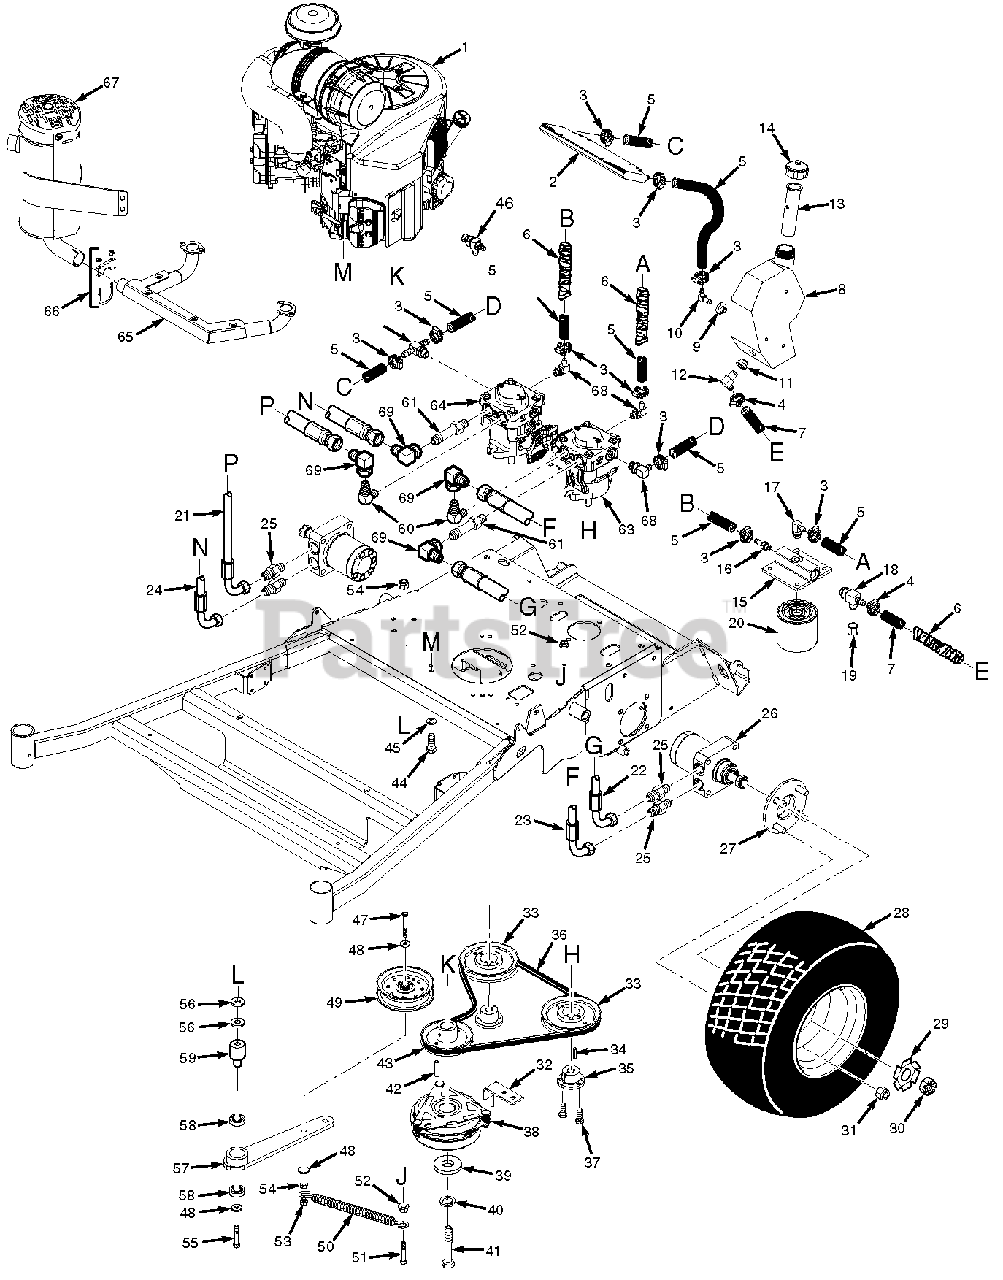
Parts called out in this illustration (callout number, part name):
1	Engine, 29hp Kawasaki FX
2	Cooler, Transmission (61V)
3	Clamp, .69 Max Dia.
4	Clamp, .87 Max Dia.
5	Hose, 3/8 Pushlock
6	Heatshield, Flexible
7	Hose, 1/2 Pushlock
8	Hydraulic Tank Assy.
9	Bushing, .56 Dia, Viton
10	Fitting, 90 Degree - .38 Hose
11	Bushing, .78 Dia. Viton
12	Fitting, 90 Degree - .50 Hose
13	Insert, Filler Neck
14	Cap, Hydraulic Tank
15	Filter Head
16	Fitting
17	Elbow, 90 Degree
18	Tee Fitting, 3/4 O-Ring
19	Cap, 3/4" JIC
20	Oil Filter
21	Hose Assembly
22	Hose Assembly
23	Hose Assembly
24	Hose Assembly
25	Fitting, Union 1/2 x 5/8
26	Wheel Motor
27	Wheel Hub
28	Wheel Assembly
28	Rim w/Valve Stem
28	Tire, 20 x 10.5-8 4-Ply
29	Lockwasher, Wheel Motor
30	Hex Castle Nut, 3/4-28
31	Wheel Nut
32	Anti-Rotation Bracket
33	Pulley, 5.45 OD - Tapered Bore
34	Key, 5 x 5 x 25mm
35	Tapered Hub, 15mm Bore
36	Belt, Pump Drive
37	Bolt, Hex Head 1/4-20 x 1" Gr. 8
38	Clutch w/Tag
39	Flatwasher, 7/16-.469 x 1.75 x .25
40	Lockwasher, 7/16" Spring
41	Bolt, Hex Head 7/16-20 x 2-1/4" Patch
42	Key, 1/4 x 1/4 x 3-1/2"
43	Pulley, 4.75 OD - 1.125" Bore
44	Bolt, Hex Head 3/8-16 x 1-1/4"
45	Lockwasher, 3/8" Spring
46	Oil Drain
47	Bolt, Hex Head 3/8-16 x 2-3/4"
48	Flatwasher, 3/8-.391 x .938 x .105 HD
49	Pulley, 4-1/2" Idler
50	Spring, Transmission
51	Bolt, Hex Head 3/8-16 x 3"
52	Nut, Serrated Flange 3/8-16
53	Nut, Center Lock 3/8-16
54	Nut, Elastic Stop 3/8-16
55	Bolt, Hex Head 3/8-16 x 3-1/4"
56	Flatwasher, 3/8-.375 x 1-1/2 x .059
57	Idler Arm Assy
58	Bearing
59	Idler Pivot, Long
60	Elbow, 90 Degree - 1/2 x 1/2
61	Fitting, Union 3/4-16 JIC x O-Ring
62	Tubing, Oil Drain
63	Pump, LH - 12cc
64	Pump, RH - 12cc
65	Exhaust Manifold, 29FX Kawasaki
66	Clamp, Muffler 1.25 Dia.
67	Muffler, 29FX Kawasaki
68	Elbow, 90 Degree
69	Elbow, 1/2 JIC Female to 1/2 JIC Male
